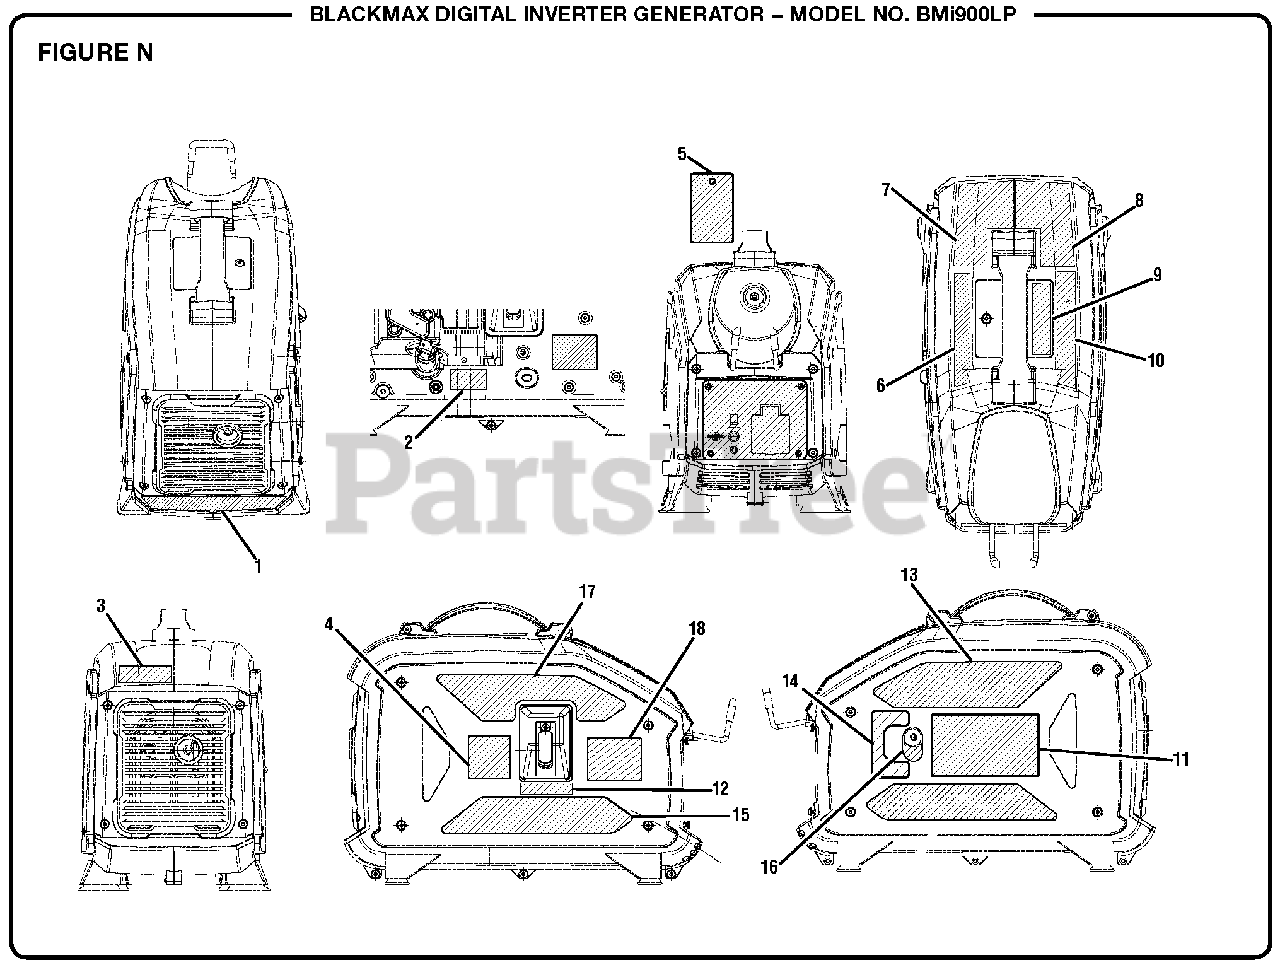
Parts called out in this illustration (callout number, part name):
1	Combustion Label
2	Maintenance Label
3	Hot Surface Label (English/Spanish)
4	Lubricant Label
5	Warning Hangtag
6	Storage Tips Label
7	CPSC Label (English)
8	CPSC Label (Spanish)
9	Inquiries Label
10	Starting Instructions Label
11	LP Warning Label
12	Primer Button Label
13	Fire Distance Label
14	Primer Button
15	Performance Label (Bottom)
16	Primer Reminder Label
17	Performance Label (Top)
18	Blackmax Logo Label
